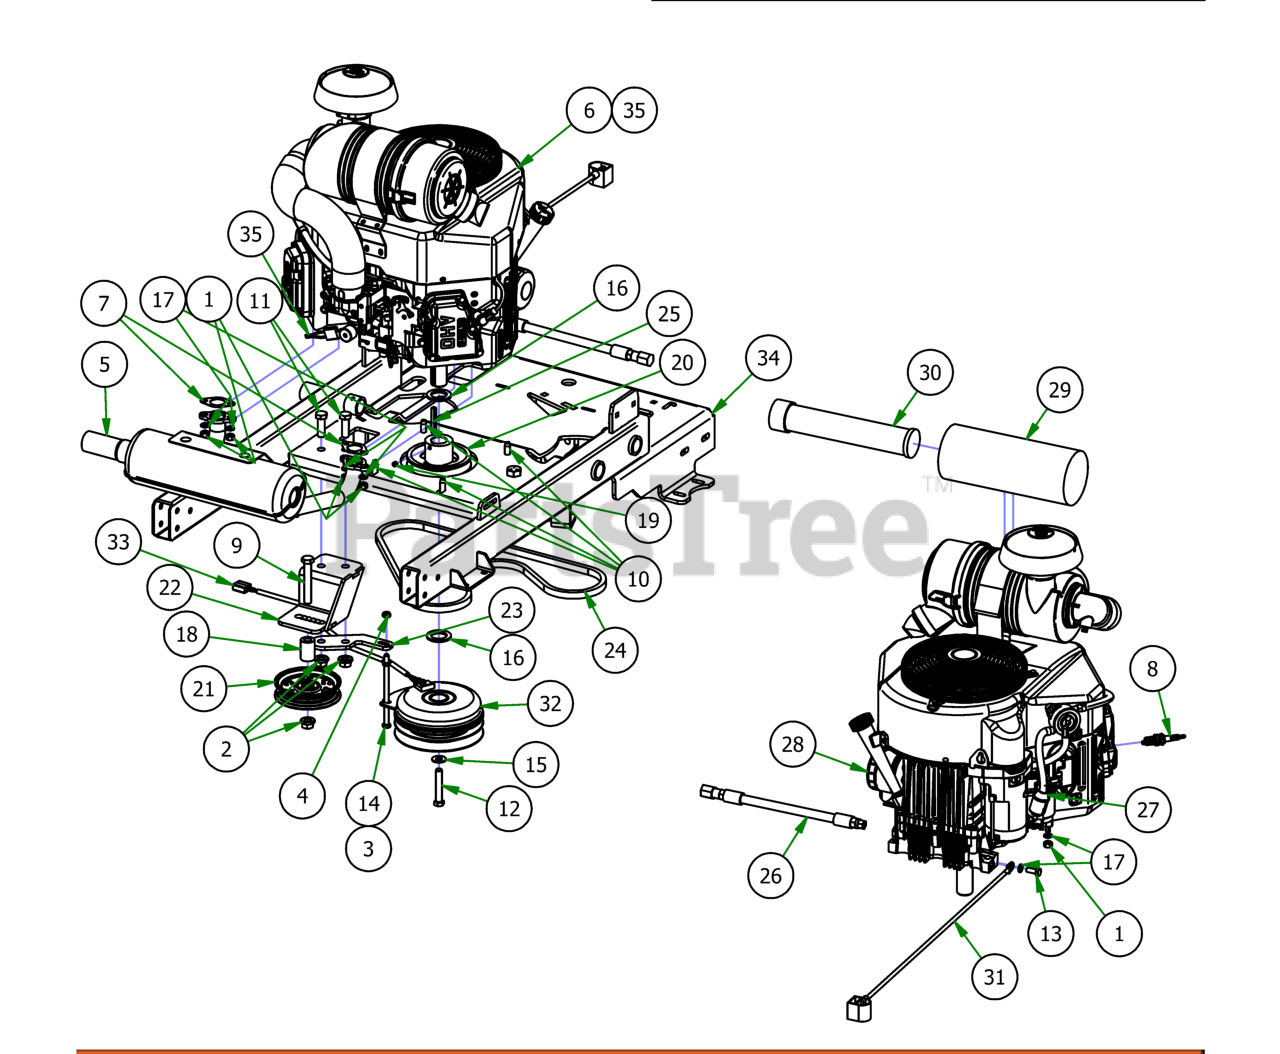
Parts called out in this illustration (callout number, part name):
1	M8-1.25 DIN 934 HEX NUT (CL.8) ZINC
2	1/2-13 NYLON INSERT FLANGE LOCKNUT ZINC
3	5/16" Flange Nut
4	5/16-18 Nylock Jam Nut 1/2 Nut
5	Exhaust-Stand On-FX691V Kawasaki
7	Exhaust Gasket
8	Spark Plug - Kawasaki
9	1/2-13 X 3-1/4 HEX CAP SCREW (GR.5) ZINC
10	3/8-16 X 1-1/8HEX WASHER UNSLOT SERRATED
11	1/2-13 X 1-1/2 HEX CAP SCREW (GR.5) ZINC
12	7/16-20 X 2-1/2 HEX CAP SCREW (GR.8) ZINC YELLOW
13	M8-1.25 X 20MM DIN 933 HEX TAP BOLT (CL 8.8) ZINC
14	5/16-18 X 5-1/2 HEX CAP SCREW (GR.5) ZINC
15	3/8 FLAT WASHER USS (1" OD) ZINC
16	1.140 ID X 1.750 OD X .132 THICK FLAT WASHER PLAIN
17	5/16 SPLIT LOCKWASHER ZINC
18	.502 ID X .750 OD X 1.500 Long Spacer
19	5/16-24 X 1/4 SOCKET SET SCREW (CUP PT) PLAIN
20	4 3/4 Motor Pulley
21	4 3/4 Idler Pulley - ABFI-76
22	Idler Pulley Bracket Weldment
23	2019 Stand On Clutch Stop Bracket
24	2019 Stand On Pump Belt (Timken# 47-2827)
25	1/4 x 2 Square key Stock
26	Kawasaki Oil Drain
27	Universal Inline Fuel Filter
28	Oil Filter
29	Canister Air Filter- Outer
30	Canister Air Filter- Inner
31	24 inch Black Cable – MZ/ZT
32	Clutch Assembly
33	Clutch Pigtail
34	2019 Stand On Frame Weldment
35	Kawasaki Harness Adapter
